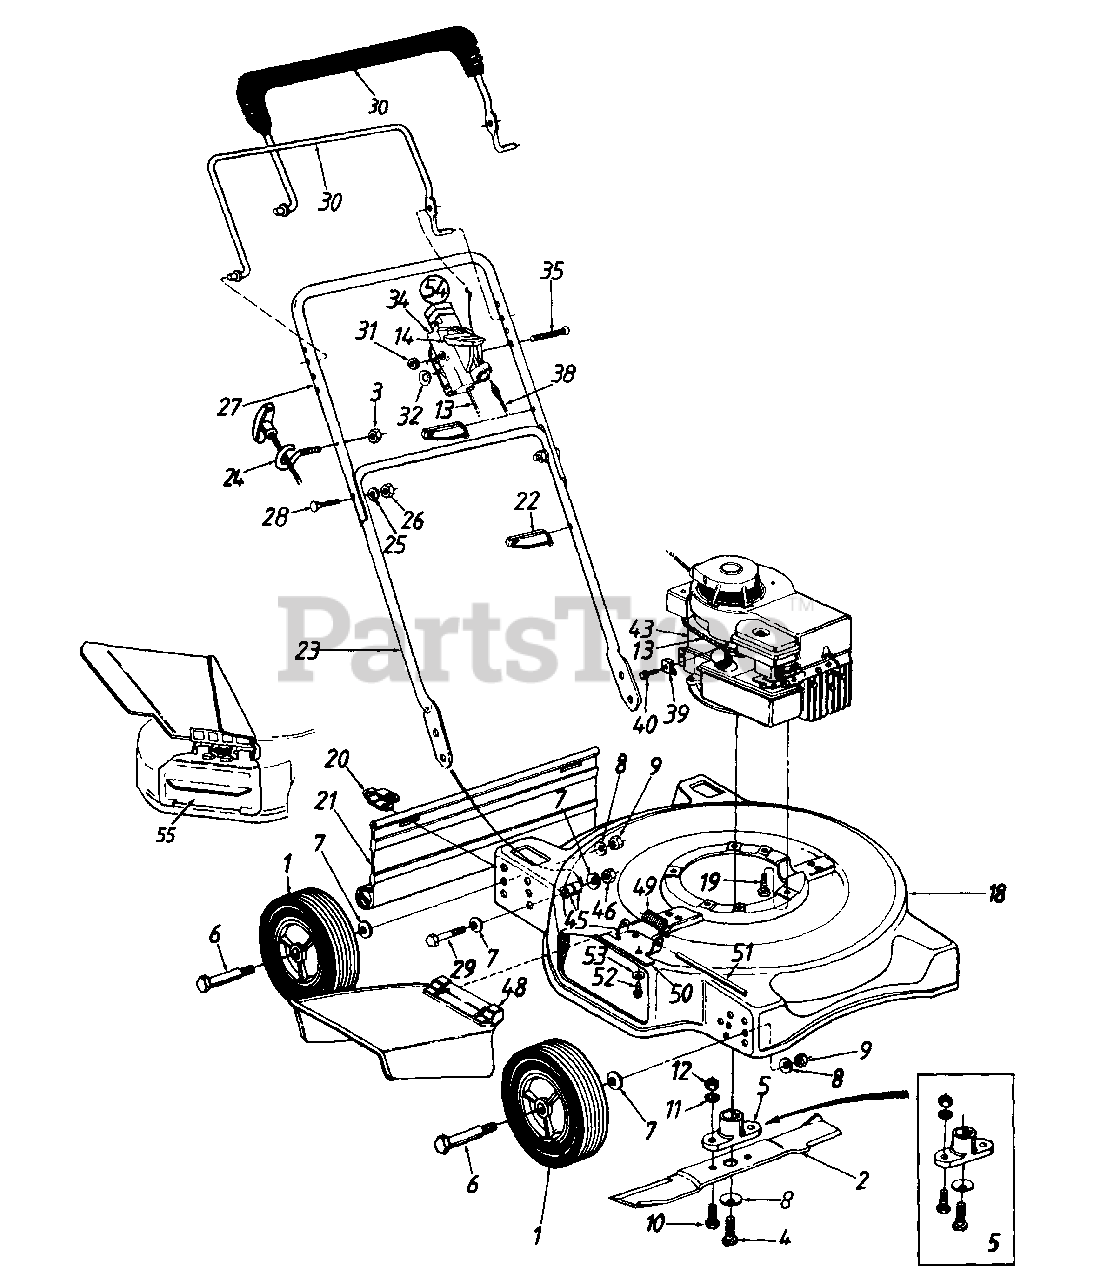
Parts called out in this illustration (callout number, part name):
1	Wheel Ass'y. Comp.
2	20" Blade
3	Hex L-Nut 1/4-20 Thd.
4	Hex Bolt 3/8-24 x 1.5" Lg.
5	Blade Adapter Kit (Keyed)
6	Axle Bolt
7	Bell-Wash .380" I.D. x .88"
8	Bell-Wash .39" I.D. x 1.13"
9	Hex Nut 3/8-16 Thd.
10	Hex Bolt 3/8-24 x 1" Lg.
11	L-Wash. 3/8" I.D.
12	Hex Nut 3/8-24 Thd.
13	Throttle Wire 51" Lg. (B&S)
14	Throttle Lever
18	20" Deck Ass'y.
19	Hex Wash. Hd. Scr. 3/8-16 x 1" Lg.
20	Hinge Clip
21	Rear Flap
22	Cable Tie
24	Rope Guide
25	L-Wash. 5/16" I.D.
26	Hex Nut 5/16-18 Thd.
29	Hex Bolt 3/8-24 x 1.5" Lg.
31	Hex L-Nut 1/4-20 Thd.
32	Spr. Wash .66" I.D.
34	Throttle Body
35	Oval C-Sunk Scr.
38	Control Cable
39	Casing Clamp (B&S)
40	Hex Wash. Hd. Scr. #10-32 x .62" Lg.
43	Engine
45	Spacer .391" I.D. x .375" Lg.
46	Hex L-Nut 3/8-24 Thd.
48	Chute Deflector Ass'y.
49	Torsion Spring
50	Adapter Plate
51	Hinge Pin
52	Hex Self-Tap Scr. 1/4-20 x .5"
53	Bell-Wash. 1/4" I.D.
54	Throttle Box Comp.
55	Mulching Plug
